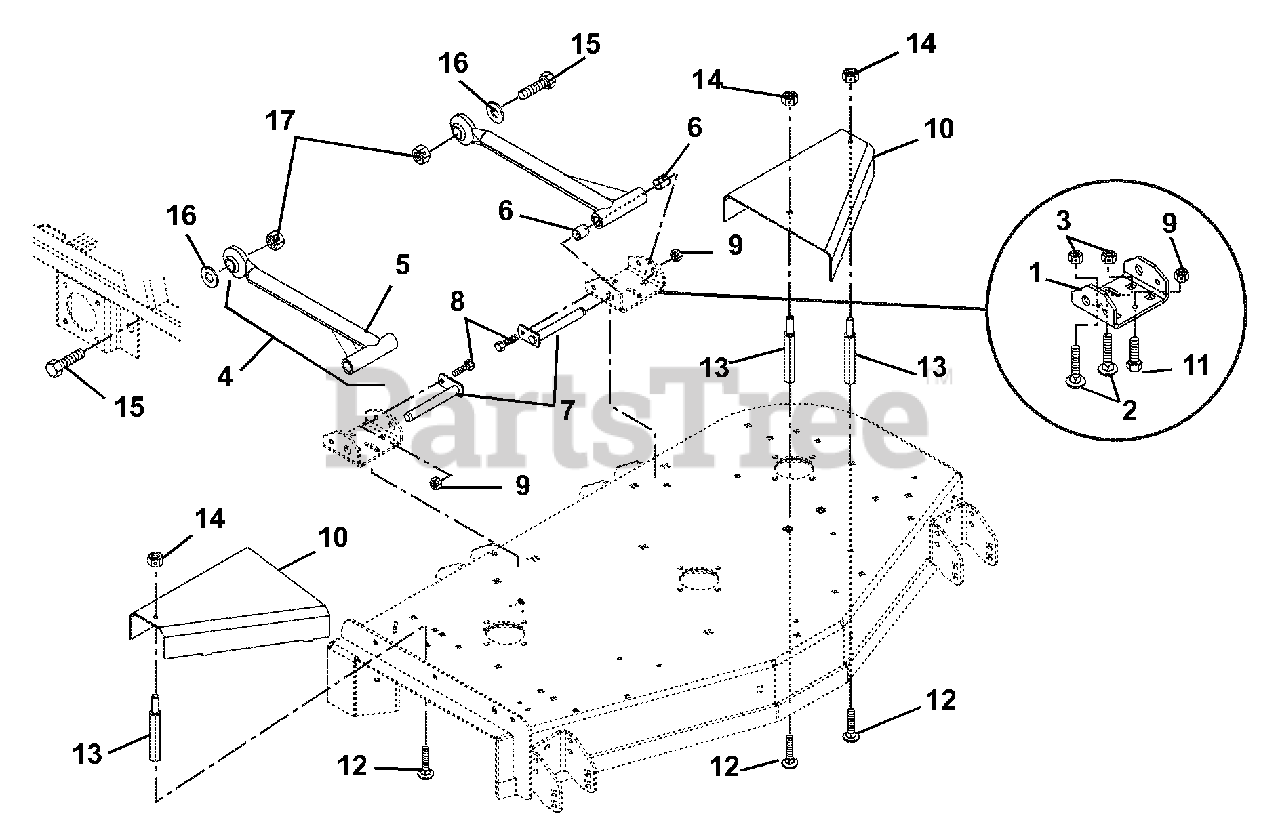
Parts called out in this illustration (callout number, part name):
1	BRACKET, MOWER MOUNT (REAR)
2	@BLT-RDHDSQNK .50-13X.75 G5YZ
3	NUT-LK-CTR-JAM .50-13 YWZC(ND)
4	ASSEMBLY, MOWER MOUNTING ARM
5	WMT, MOWER MTG ARM - BLACK
6	BRG, .750 X .875 X 1.000
7	WELDMENT, MOWER MTG. PIN
8	@BLT-HEX .38-16X1.00 GR5 YWZC
9	@NUT-LK-TOP-FLG .38-16 YWZC
10	GUARD, PULLEY LH
11	@BLT-RDHDSQNK .38-16X.75 G5YZ
12	BLT,RDHDSQNK .31-18X.75 LOCTIT
13	STANDOFF, 2.75 X 5/16-18
14	@NUT-LK-TOP-FLG .31-18 YWZC
15	BLT-HEX .875-9X2.75 GR5 YWZC
16	WSHR-FL-STL .890X1.500X.1196YZ
17	NUT-LK-CTR .875-9 YWZC
